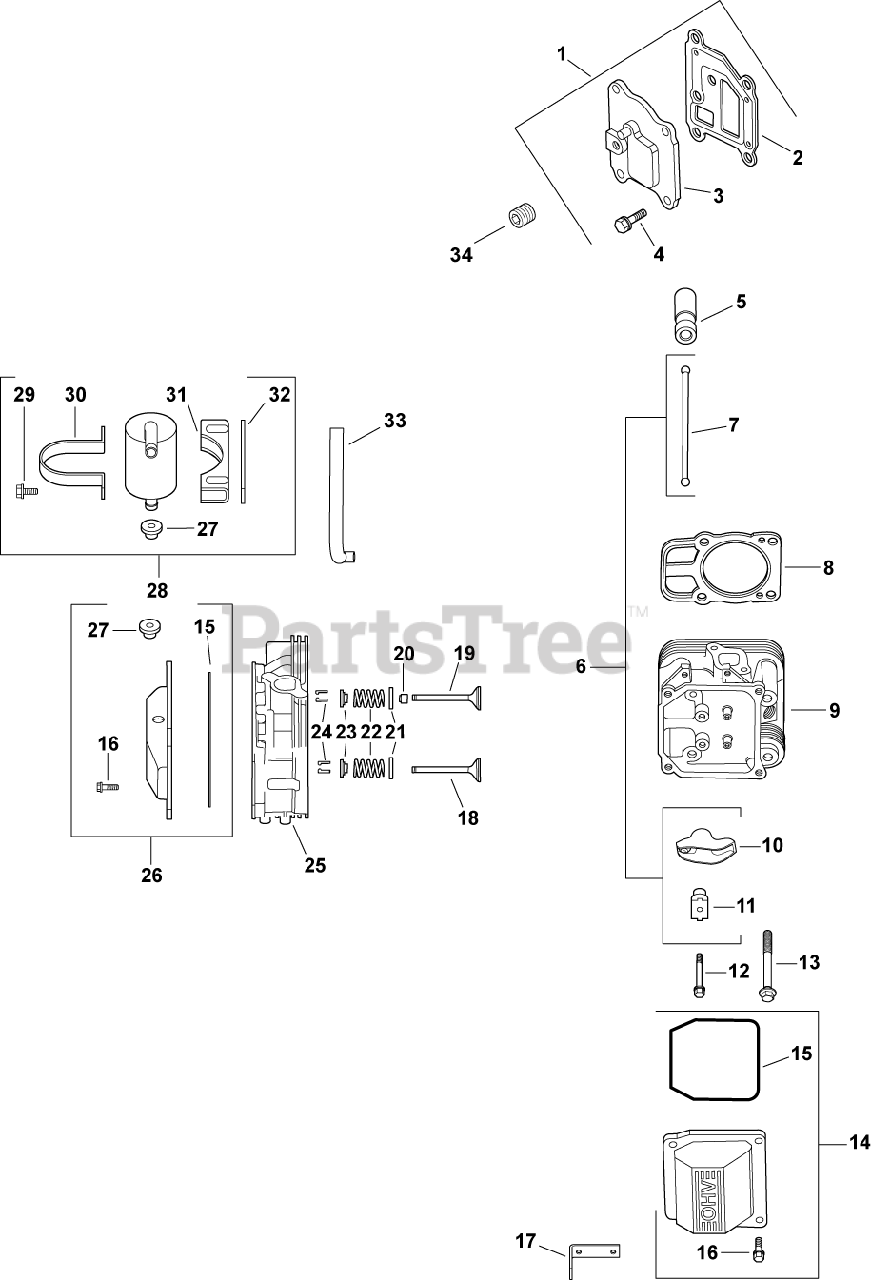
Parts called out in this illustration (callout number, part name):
1	KIT, BREATHER COVER W/GASKET
2	GASKET, BREATHER-USE 24 041 67-S
3	COVER, BREATHER -USE 24 096 125-S
4	SCREW,FLG THD FRM M6X1.0X20-(#25086396S)
5	LIFTER, HYDRAULIC VALVE-USE 25 351 10-S
6	KIT, VALVE TRAIN
7	ROD, PUSH
8	KIT, CYL HEAD GASKET (C17-22)
9	HEAD, ASSEM CYLINDER #2 -USE 24 318 113-
10	ARM, ROCKER
11	PIVOT, ROCKER ARM
12	SCREW, FLG M6X1.0X34
13	SCREW - USE 62 086 08-S
14	KIT, VALVE COVER-PLAIN
15	O-RING (YELLOW) -USE 24 153 30-S
16	SCREW, FLG M6X1.0X30
17	STRAP, LIFTING-USE 25 445 03-S
18	VALVE, EXHAUST (STD) - USE 32 016 01-S
19	VALVE, INTAKE (STD)
20	SEAL, VALVE STEM - (#2503214S)
21	RETAINER, SPRING
22	SPRING, VALVE
23	RETAINER, VALVE SPRING - USE 25 173 28-S
24	KIT, RETAINER
25	HEAD, ASSEM CYLINDER #1 -USE 24 318 105-
26	KIT, VALVE COVER
27	GROMMET, RUBBER
28	KIT, BREATHR SEPARATR-(#24755241S)
29	SCREW,FLG THD FRM M5X0.8X16-(#25086398S)
30	STRAP, BREATHER - USE 24 755 241-S
31	BRACKET, BREATHER SEPARATOR
32	SPACER
33	HOSE, BREATHER-USE 24 326 93-S
34	PLUG, CTSK PIPE 1/8"
2401602-S	VALVE, EXHAUST (.25)
2401702-S	VALVE, INTAKE (.25)
